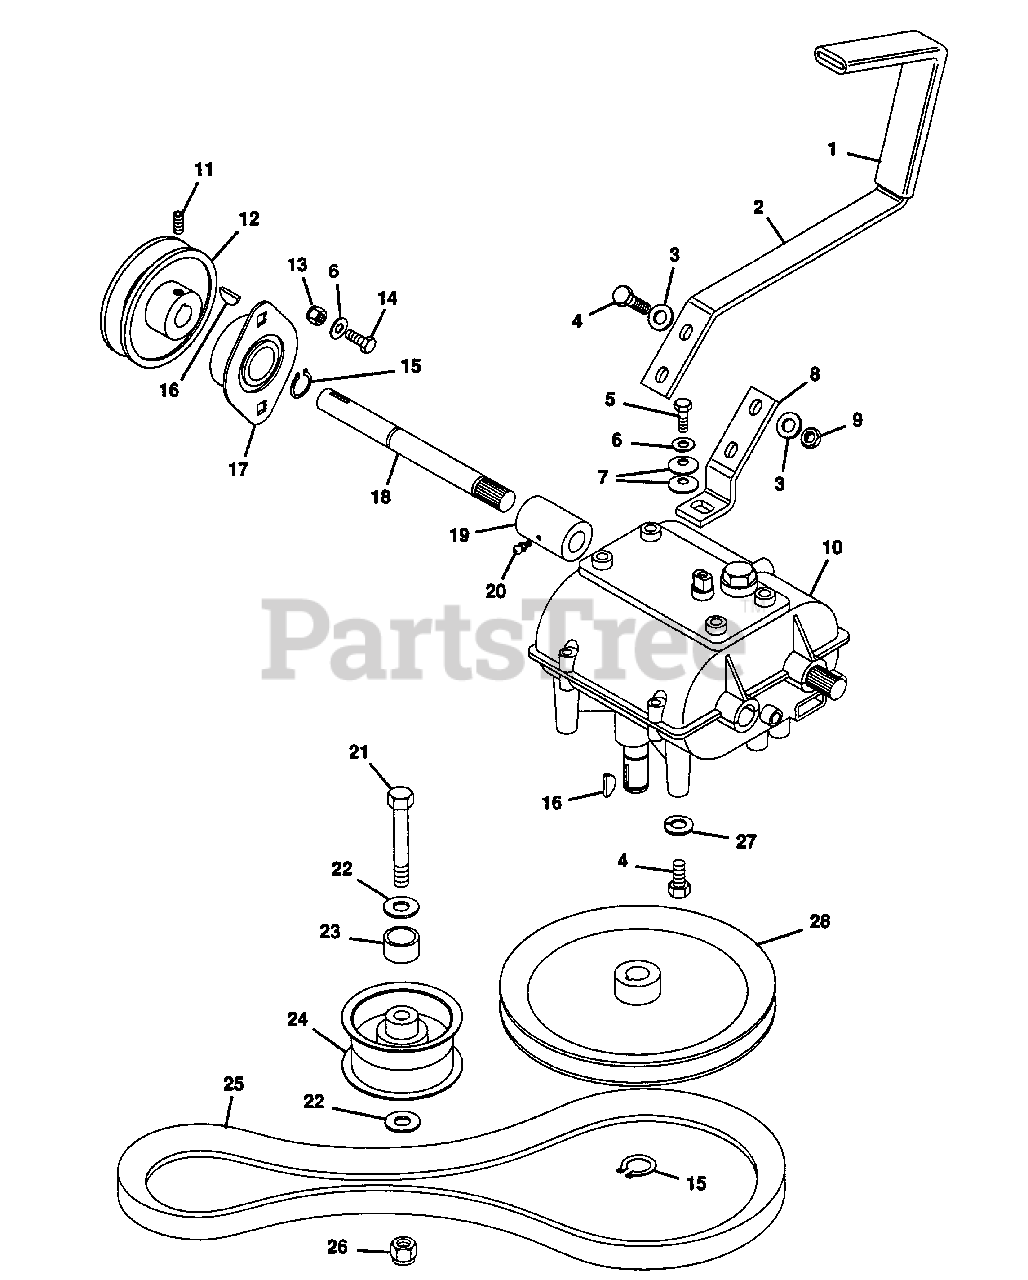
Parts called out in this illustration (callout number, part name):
1	GRIP
2	LEVER, TRANSMISSION SHIFT
3	WASHER, FLAT .344X.688X.065
4	BOLT, HEX 5/16-18X1.00
5	BOLT, HEX 1/4-28X.75 GR. 8
6	WASHER, FLAT .281X.625X.065
7	WASHER, BELLEVILLE
8	ARM, TRANS. SHIFT
9	NUT, LOCK 5/16-18
10	TRANSMISSION, 5-SPEED PRO 32
11	SCREW, SET 1/4-20X.375 HSCT
12	SHEAVE, TRANSMISSION SHAFT EXT.
13	NUT, LOCK 1/4-20
14	BOLT, HEX 1/4-20X.750
15	RING, RETAINING
16	KEY, WOODRUFF .187X.75 HARD #9
17	BEARING, FLANGED
18	SHAFT, TRANSMISSION EXTENSION
19	COUPLER, TRANSMISSION SHAFT
20	FITTING, LUBE 1/4-28
21	BOLT, HEX 3/8-16X2.25
22	WASHER, FLAT .406X.812X.065
23	SPACER, .625X.385X.55
24	PULLEY, IDLER
25	BELT-V, ENGINE TO TRANSMISSION
26	NUT, LOCK 3/8-16
27	WASHER, LOCK 5/16 REG.
28	SHEAVE, TRANSMISSION
